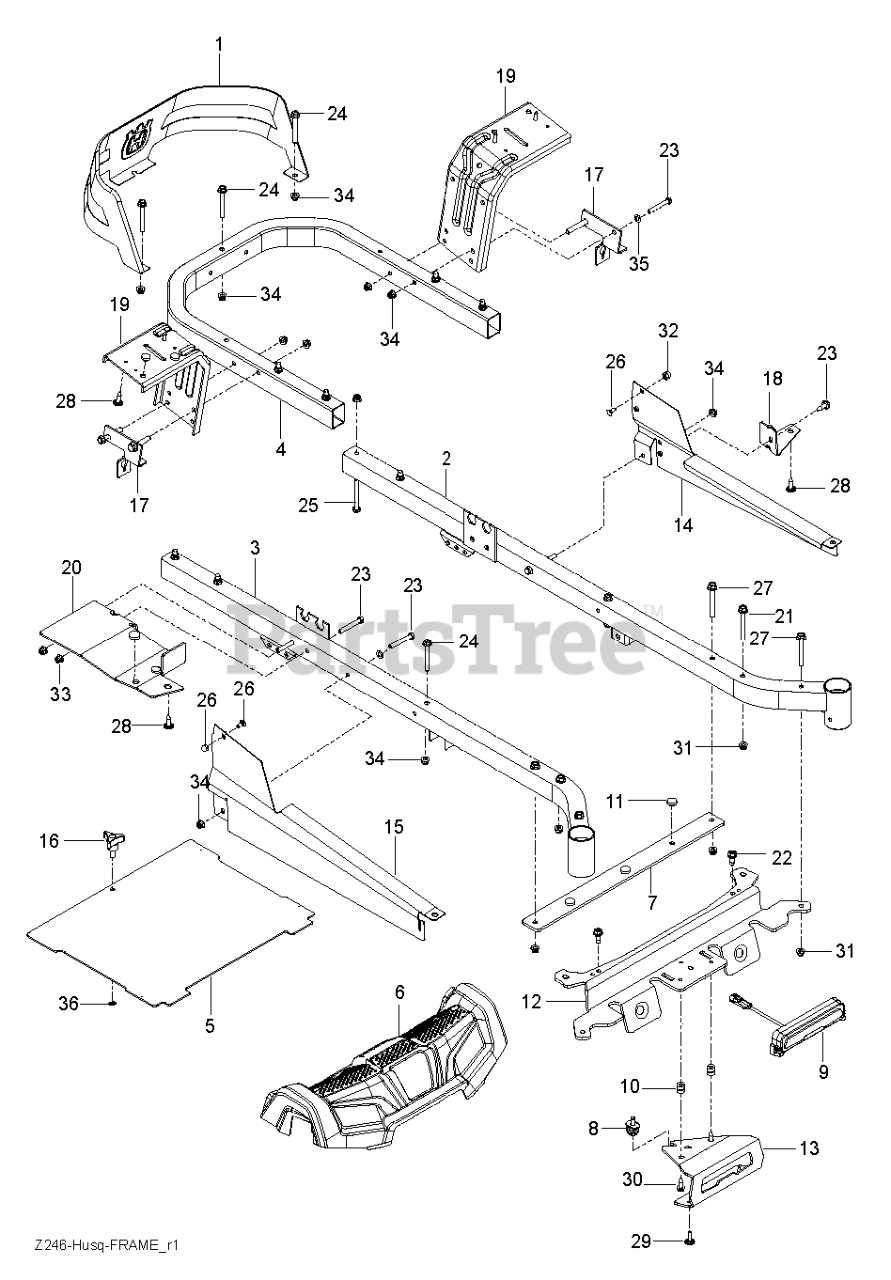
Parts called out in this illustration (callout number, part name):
1	GUARD.ENGINE.HUSQ.RZ.X498
2	FRAME.TUBE.RZ.MAIN.WELD.LH.ORG
3	FRAME.TUBE.RZ.MAIN.WELD.RH.ORG
4	TUBE.PNT.FRAME.RER.HUSQ.23".RZ
5	SUPPORT.RZ.FOOTREST.PLATE.X43
5	PLATE, FOOT W/DECALS RZ
6	COVER.FOOTREST.REFRESH.ASM
7	FOOTREST.PLATE.SUPPORT.X431
8	SCREW.ADJ.ISOLATOR.BOLT.ASSY
9	LIGHT.ZTR.LED.ASM
10	GROMMET.RUBBER.PUSHIN
11	GROMMET.BUMPER
12	CROSS.PNT.MEMBER.BLK
13	SKID PLATE RZ REFRESH STANDARD
13	BRACKET.SKIDPLTE.LED.RFRSHX417
14	COVER.RAIL.RH.RZ.X668
15	COVER.RAIL.LH.RZ.X668
16	KNOB W/STUD
17	BRKT ROD.BYPASS.EZT.X431
18	SUPPORT.PNT.LH.CONSOLE.FRONT
18	SUPPORT RZ REFERSH LH CONSOLE
19	FENDER.SUPPORT.PNT.X431
20	SUPPORT.PNT.RH.CONSOLE.FRONT
21	BOLT SHOULDER,FLANGED,3/8-16X3
22	BOLT.5/16-18.THRD.ROLL.SHOULDR
23	BOLT.FIN HEX 5/16-18UNC X2 1/4
25	BOLT.HEX.FIN.3/8-16 X 3.GR5
26	BOLT.CARRIAGE.5/16-18.7/16
27	HHFS 3/8-16 X 3 GRD 5 ZD
28	SCREW.#10 X 0.750.BOS
29	SCREW.#10 X 0.500
30	BOLT.5/16-18X1.25
31	NUT 3/8-16 HEX FLG NYLOC ZD
32	NUT ACORN,FLANGED,5/16-18
33	NUT LOCK HEX FLANGE 5/16-18
34	5/16-18 NYLOC FLANGE NUT
35	WASHER
36	WASHER 5/16"
